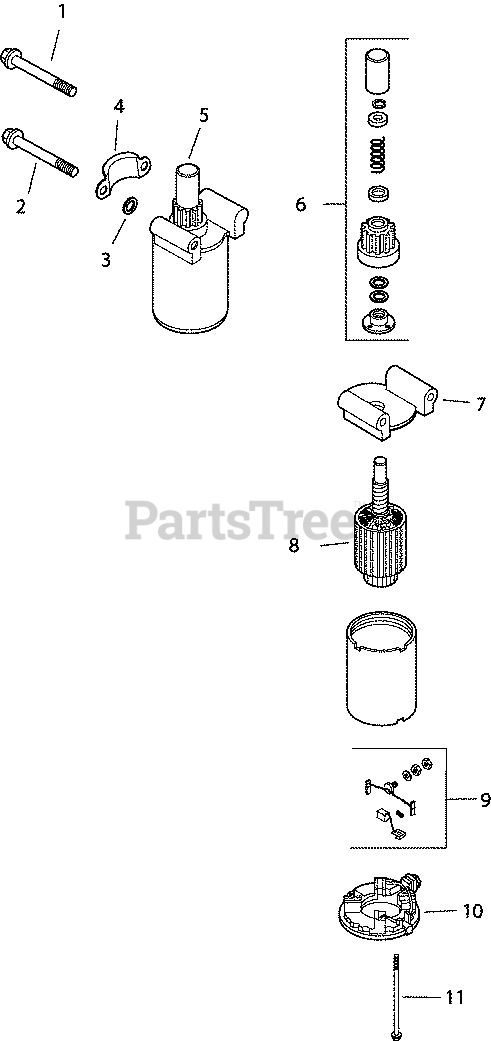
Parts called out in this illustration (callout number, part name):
1	SCREW - USE M-851080-S
2	SCREW, FLG M8X1.25X70
3	WASHER, FLAT 11/32"
4	COVER, PINION
5	ELECTRIC STARTER-BENDIX DRIVE
6	KIT, DRIVE
7	CAP, DRIVE END - (#DSC)
8	ARMATURE - DISCONTINUED
9	BRUSH KIT - (#DSC)
10	CAP - DISCONTINUED
11	BOLT, THRU #10-24X4 13/32" - DISCONTINUED
